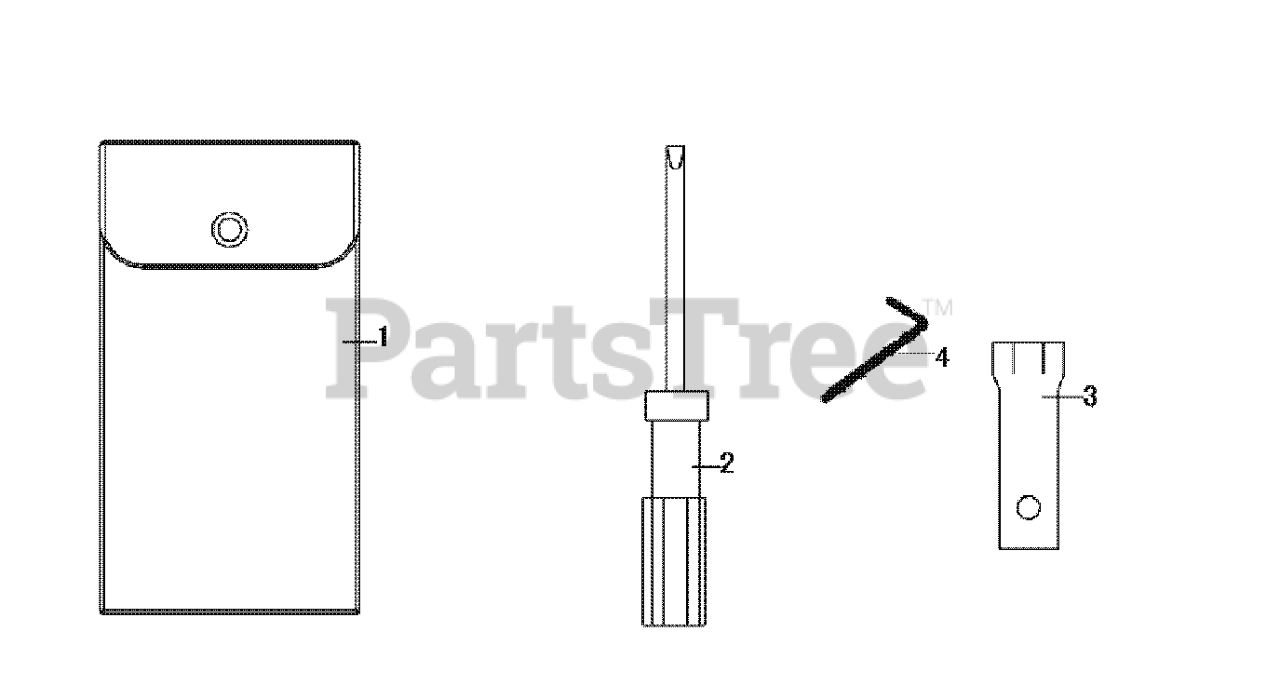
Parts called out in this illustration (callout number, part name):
1	BAG, TOOLS
2	SCREW DRIVER
3	SOCKET, SPARK PLUG
4	ALLEN WRENCH
